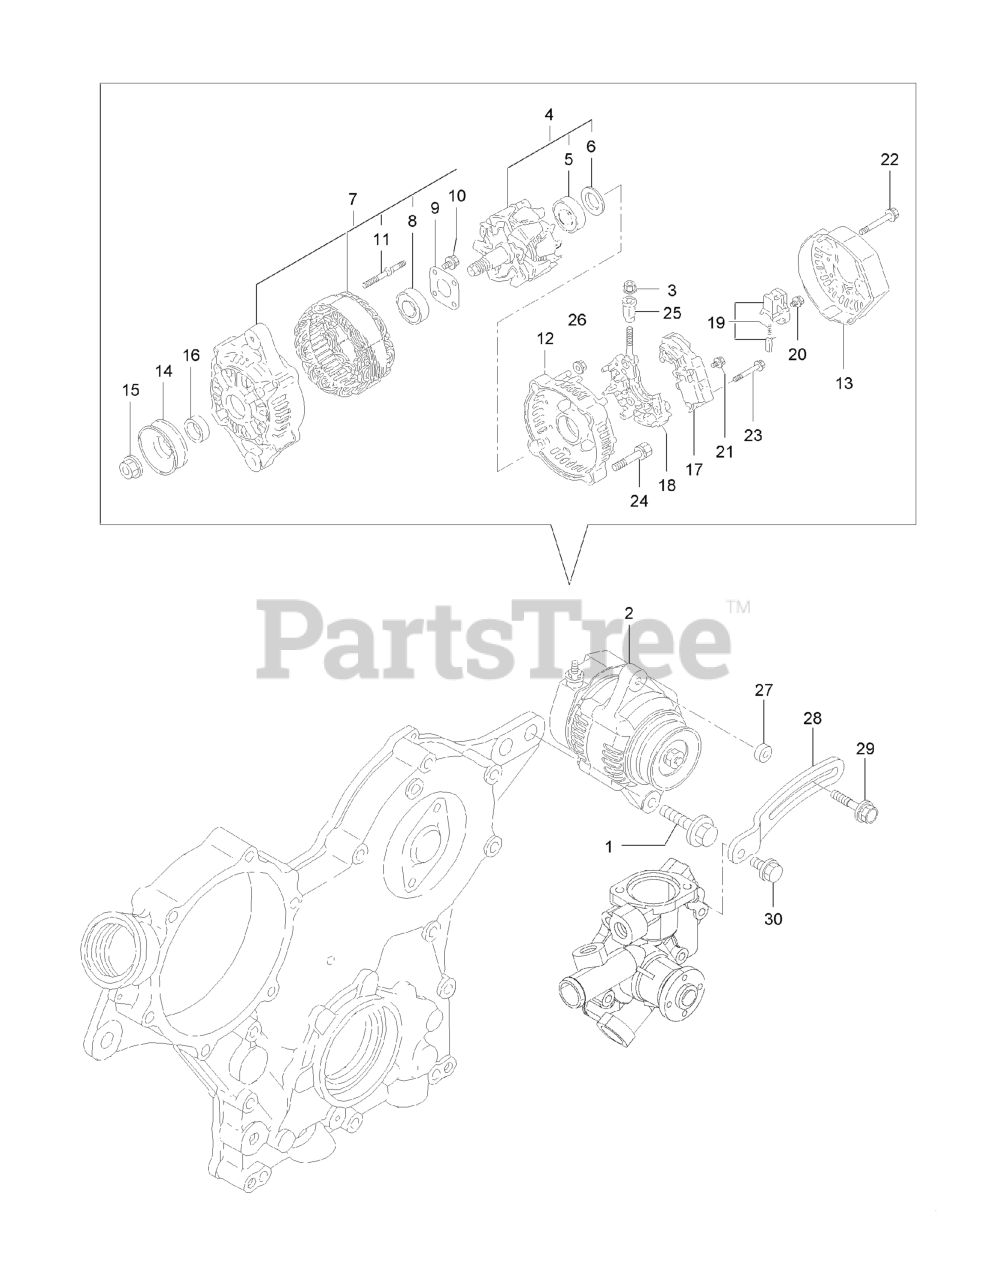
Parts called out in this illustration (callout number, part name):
2	ALTERNATOR
4	Rotor ASM
5	BEARING-BALL
7	FRAME ASM
8	BEARING-BALL
9	Plate-Retainer
17	REGULATOR ASM
25	Bushing-Insulation
28	ADJUSTER-BELT
